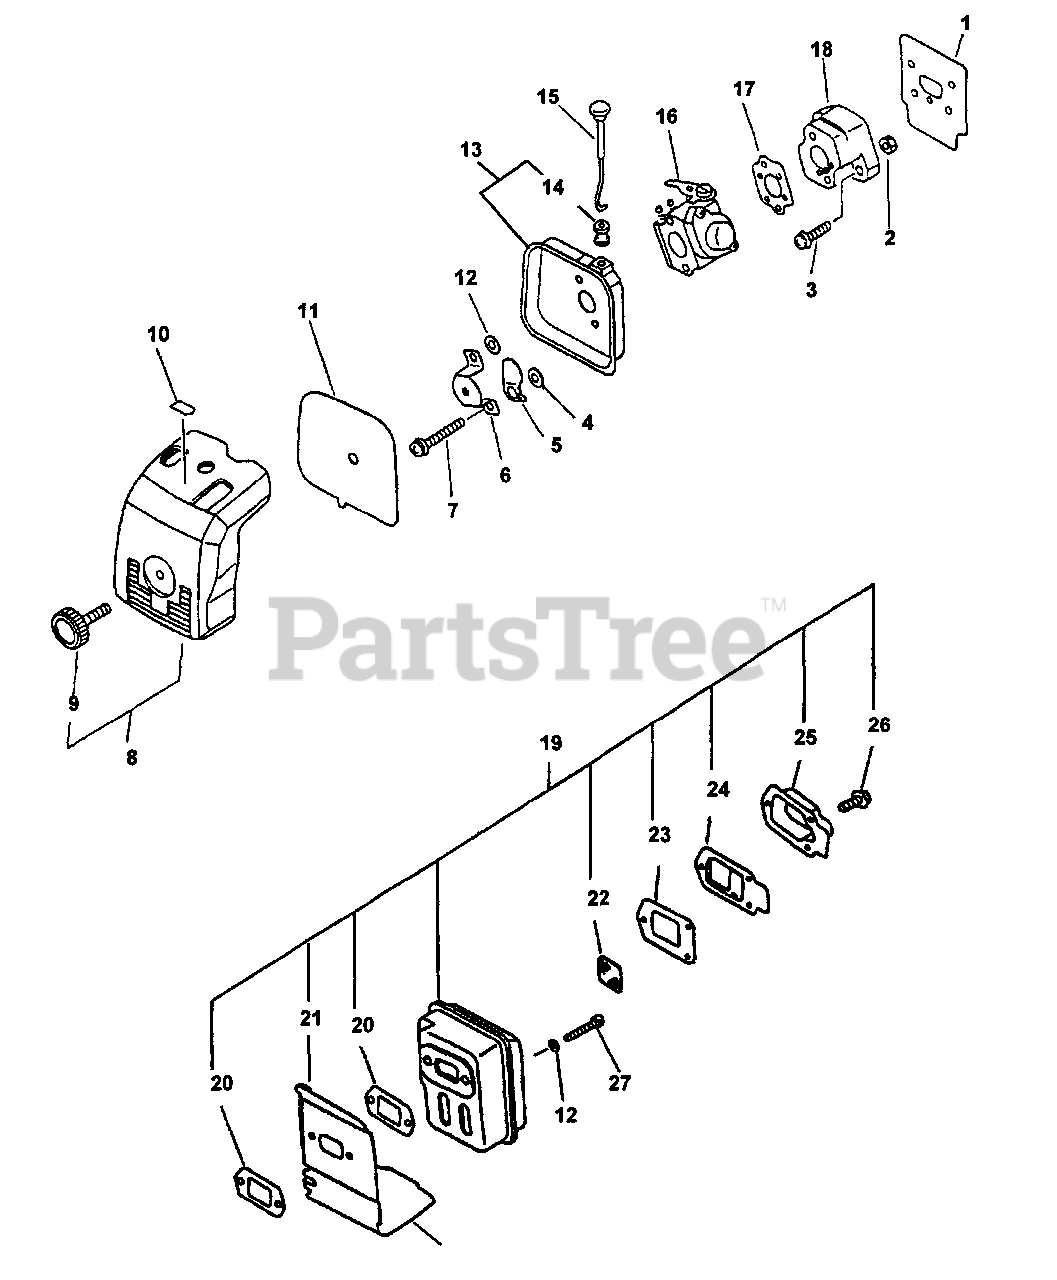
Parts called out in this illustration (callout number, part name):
1	HEAT SHIELD, INTAKE
2	NUT M5
3	SCREW 5×20
4	WASHER 5.2×8×0.8T
5	SHUTTER, CHOKE
6	PLATE, PREVENT
7	SCREW 5×57
8	AIR FILTER COVER ASSY
9	THUMBSCREW
10	LABEL, CHOKE
11	FILTER, HEAVY-DUTY AIR
12	WASHER, FLAT 5.5×10×0.8
13	CASE ASSY, AIR FILTER
14	GROMMET, CHOKE
15	ROD, CHOKE
16	CARBURETOR - WT-424A
17	GASKET, CARBURETOR
18	INSULATOR, INTAKE
19	MUFFLER ASSY
20	GASKET, EXHAUST
21	COVER, EXHAUST
22	SCREEN, SPARK ARRESTER
23	GASKET, EXHAUST
24	GUIDE, EXHAUST
25	OUTLET, EXHAUST
26	SCREW 4×10
27	BOLT 5×55
